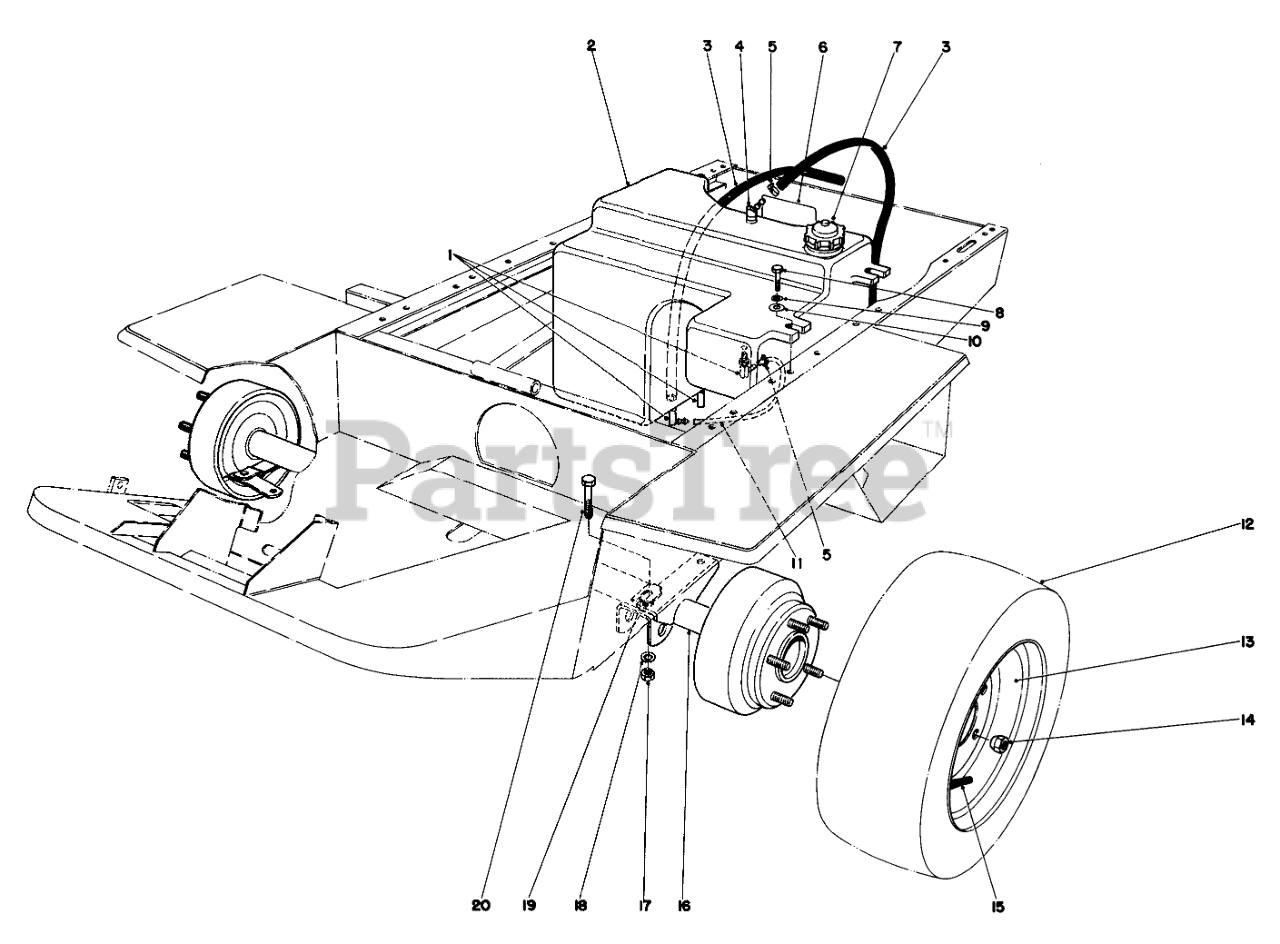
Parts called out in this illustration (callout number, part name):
1	FITTING-ELBOW, 90 DEG
2	Gas Tank (Incl. Ref. #1 & 3)
3	GAS TANK VENT HOSE
4	ELBOW
5	CLAMP-HOSE
6	DECAL-DANGER
7	GAS CAP ASSEMBLY
8	SCREW-HH
9	WASHER-LOCK
10	WASHER
11	Hose-Fuel
12	20 X 8.00 - 10 TIRE
13	WHEEL ASM
14	NUT-WHEEL
15	VALVE STEM AND CAP ASM
17	NUT-HEX
18	WASHER-LOCK
19	SHIM-AXLE
20	SCREW-HH
